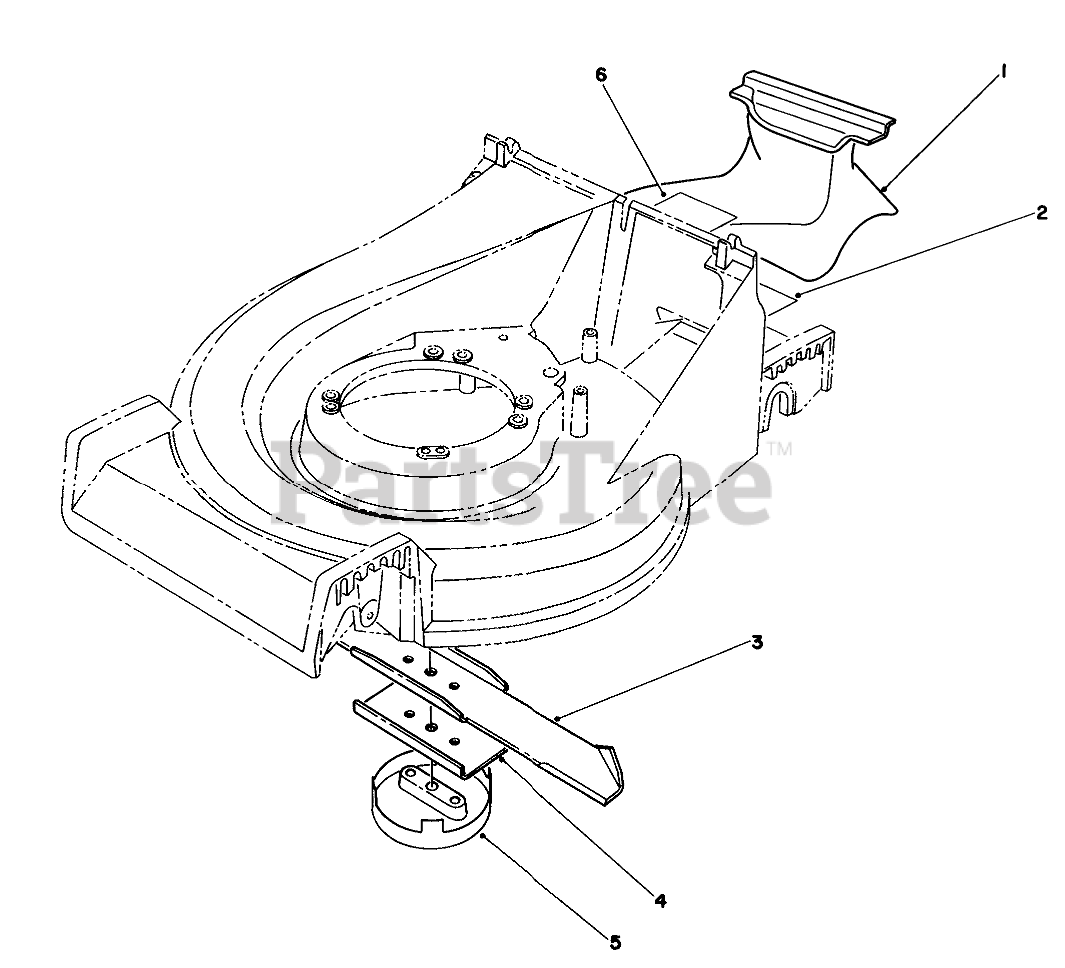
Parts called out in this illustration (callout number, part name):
1	RECYCLER PLUG
2	DECAL - MULCHER KIT
3	BLADE-21in
4	Stiffener
5	CUP-SCALP, ANTI
6	DECAL - FRENCH
